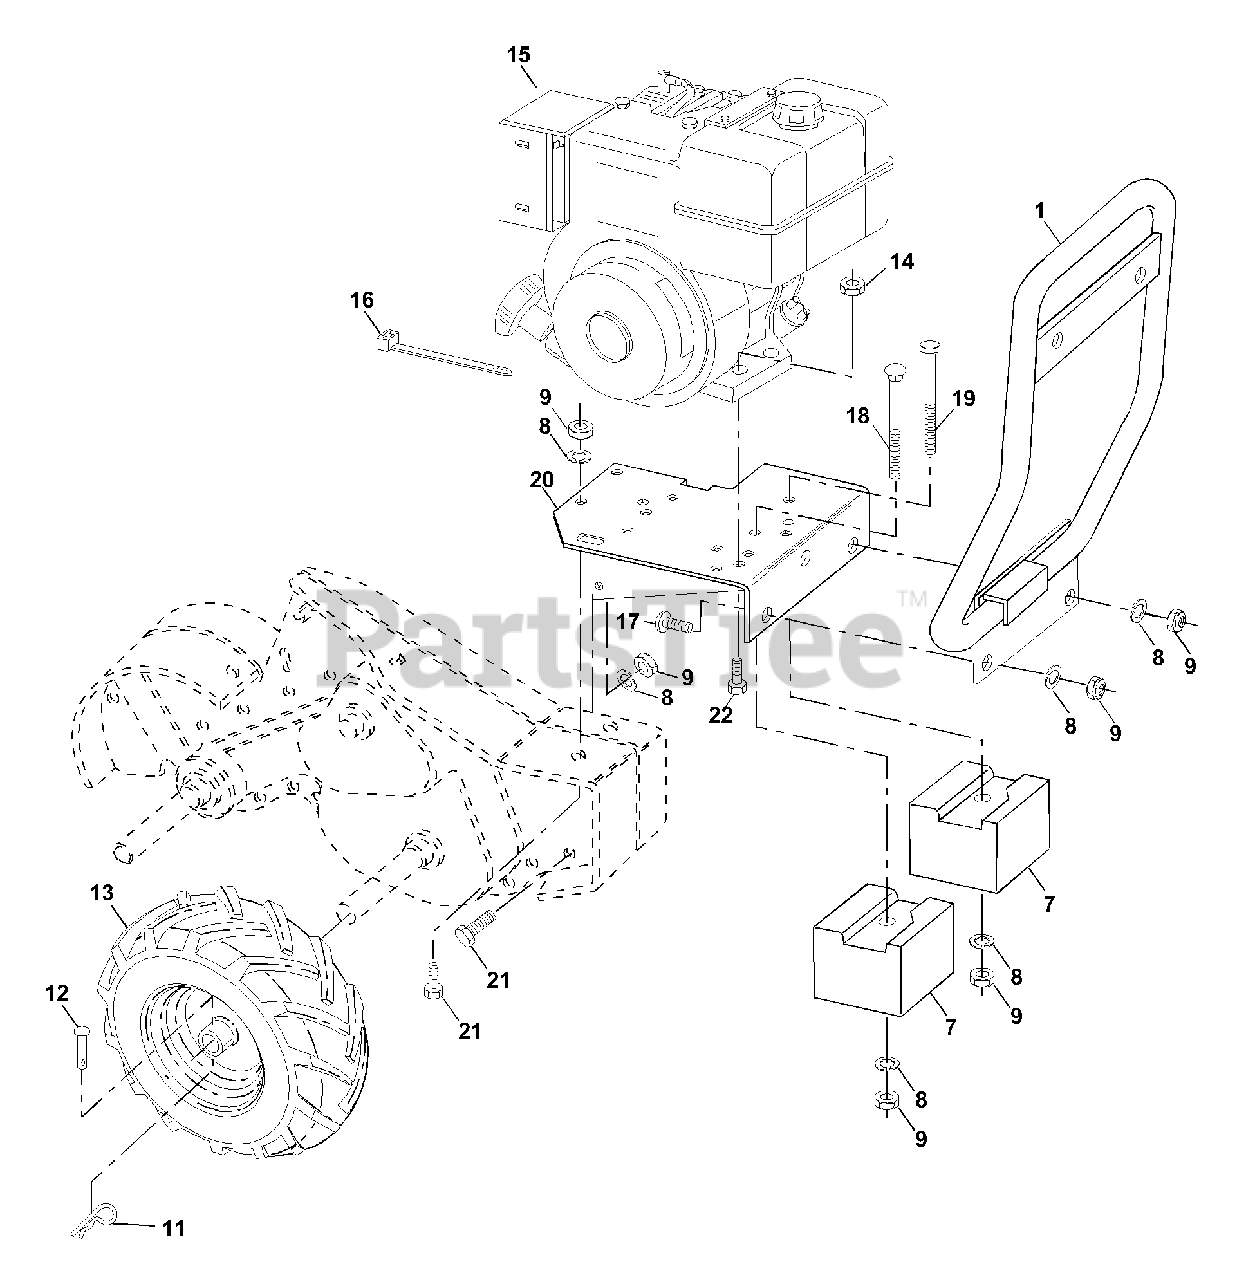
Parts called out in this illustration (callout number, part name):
1	Bumper
7	Counter Weight, R.H.
8	Washer, Lock 3/8
9	Nut, Hex 3/8-16
11	Clip, Hairpin
12	Rivet, Drilled
13	Tire
13	Rim
13	Tire Valve
14	Nut, Keps 5/16-18
16	Tie, Cable
17	Bolt, Carriage 3/8-16 x 1
18	Bolt, Carriage 3/8-16 x 4-1/2
19	Bolt, Hex Head 3/8-16 x 4-1/2
20	Bracket, Engine
21	Bolt, Hex Head 3/8-16 x 1
22	Bolt, Hex 5/16-18 x 1-3/4
